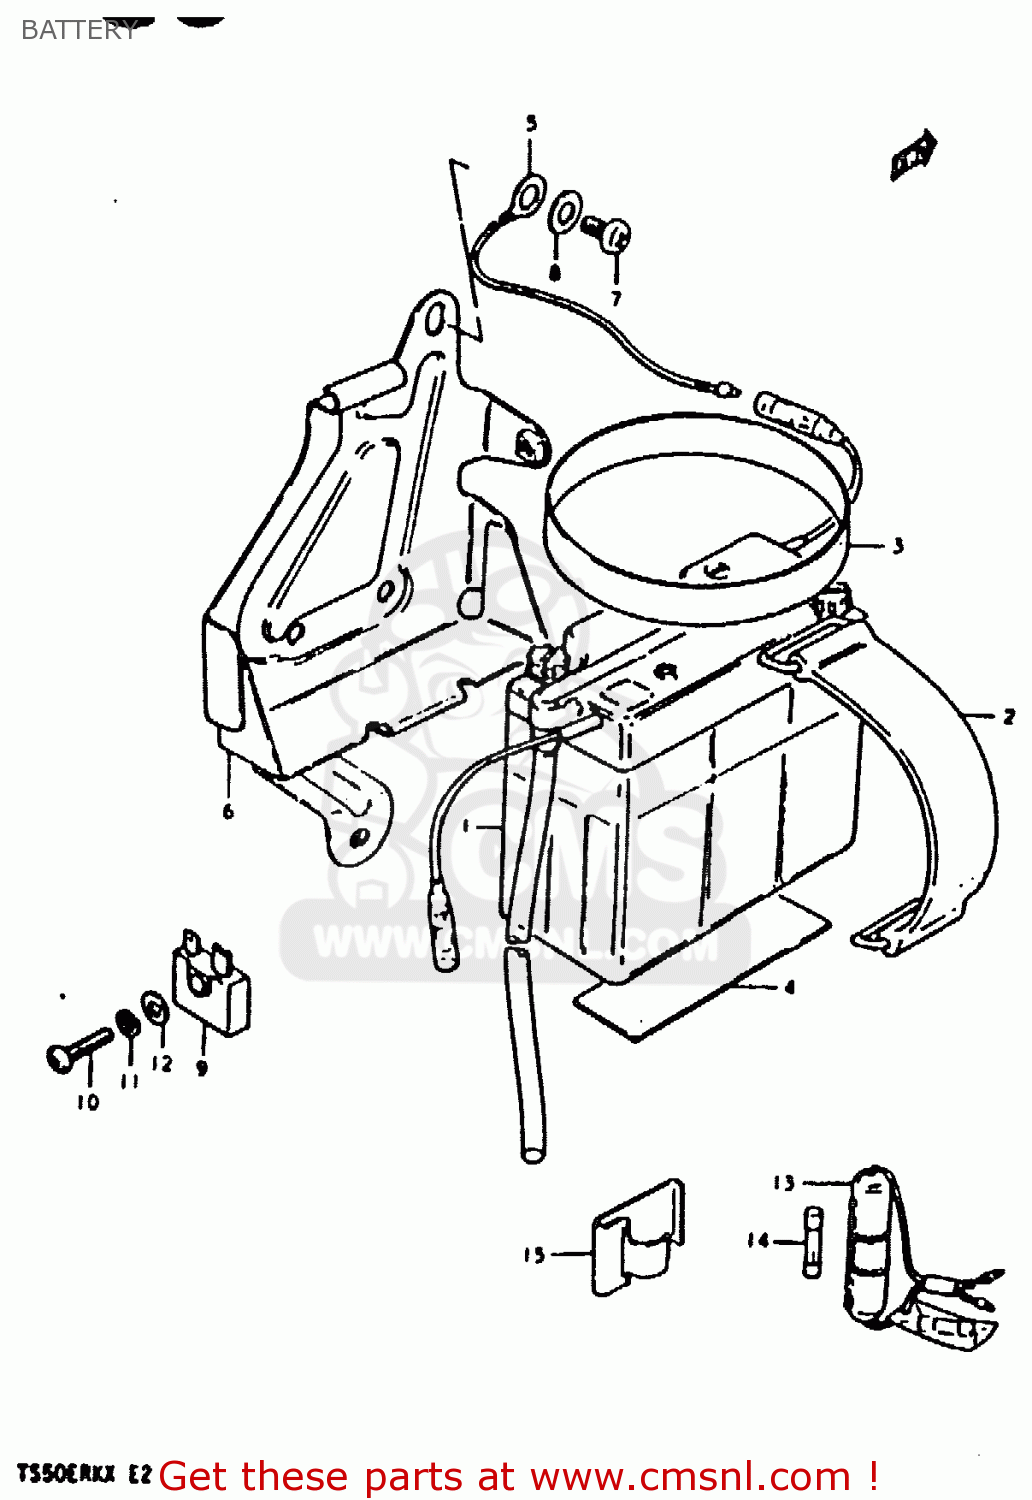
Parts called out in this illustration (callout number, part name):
1	BATTERY(6N4B-2A,6V4.2AH)
2	BAND
3	PROTECTOR,BATTERY
4	PROTECTOR(30X80X2)
5	LEAD WIRE
6	HOLDER, BATTERY
7	SCREW 6X12
8	WASHER
9	RECTIFIER ASSEMBLY
10	SCREW 5X20
11	LOCK WASHER
12	WASHER
13	BOX ASSEMBLY,FUSE
14	FUSE(10A)
15	HOLDER,FUSE CASE
